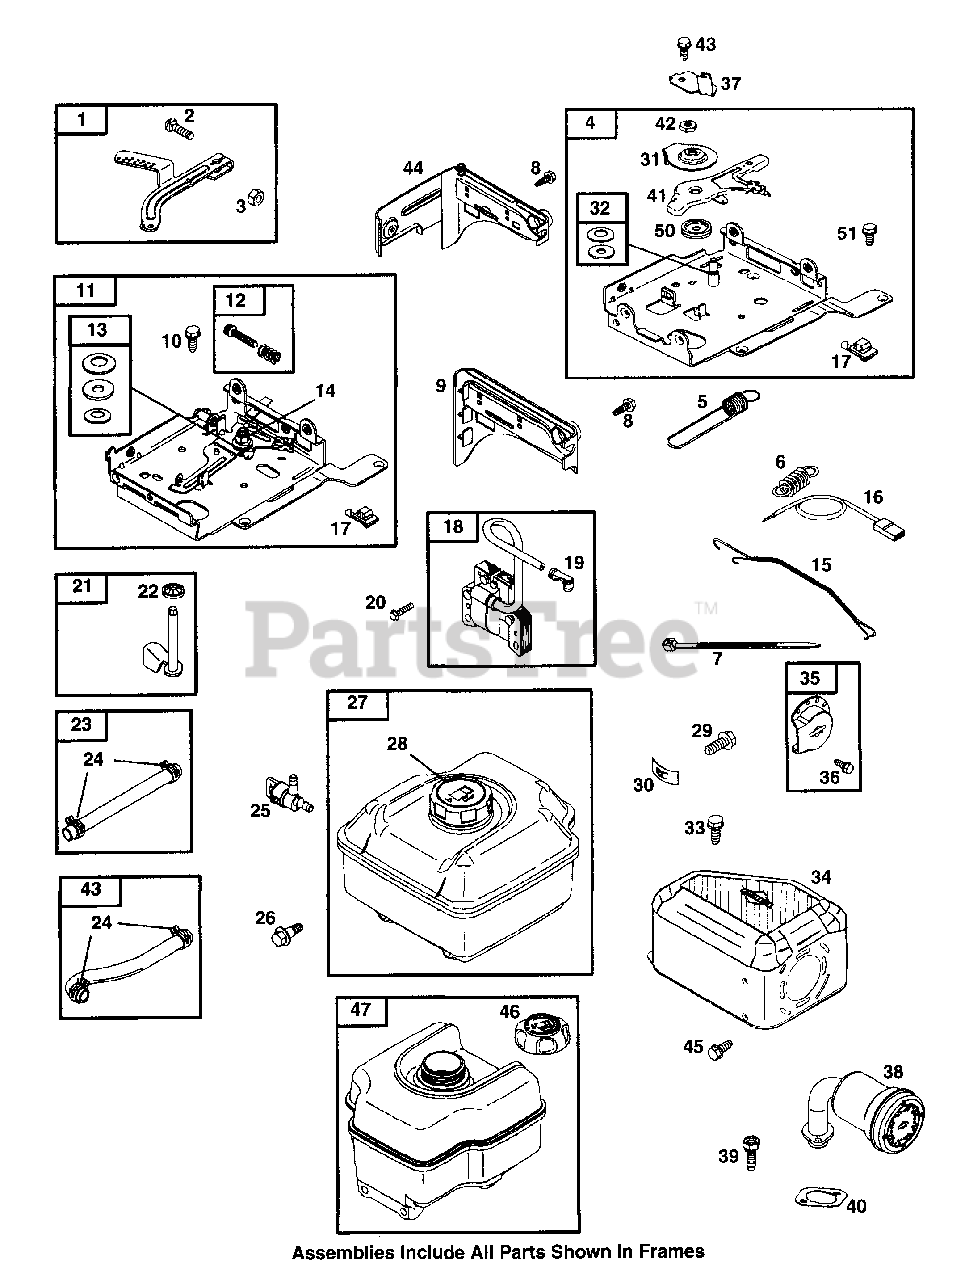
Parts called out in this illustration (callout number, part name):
1	Governor Lever
2	Bolt (Governor Control Lever)
3	Nut (Governor Control Lever)
4	Control Brkt
5	Governor Spring
6	Governor Spring
8	Screw (Control Panel)
9	Control Panel
10	Screw (Control Bracket)
11	Control Brkt
12	Idle Speed Kit
13	Washer Set
14	Nut (Control Brkt)
15	Spring/Link (Mechanical Governor)
17	Switch-Stop
18	Armature-Magneto
19	Sparkplug Terminal
20	Screw (Magneto Armature)
21	Crank-Governor
22	Governor Shaft Retainer
23	Fuel Line
24	Clamp-Hose
25	Fuel Shutoff Valve
26	Screw (Fuel Tank)
27	Fuel Tank
28	Fuel Tank Cap
29	Screw (Fuel Tank)
31	Retainer
32	Washer Set
33	Screw (Muffler Guard)
34	Muffler Guard
35	Muffler Deflector
36	Screw (Muffler Deflector)
37	Fixed Brkt
38	Exhaust Muffler
39	Screw (Exhaust Muffler)
40	Exhaust Gasket
41	Control Lever
42	Nut (Control Brkt)
43	Fuel Line (Molded)
44	Control Panel
45	Screw (Muffler Guard)
46	Fuel Tank Cap
47	Fuel Tank
